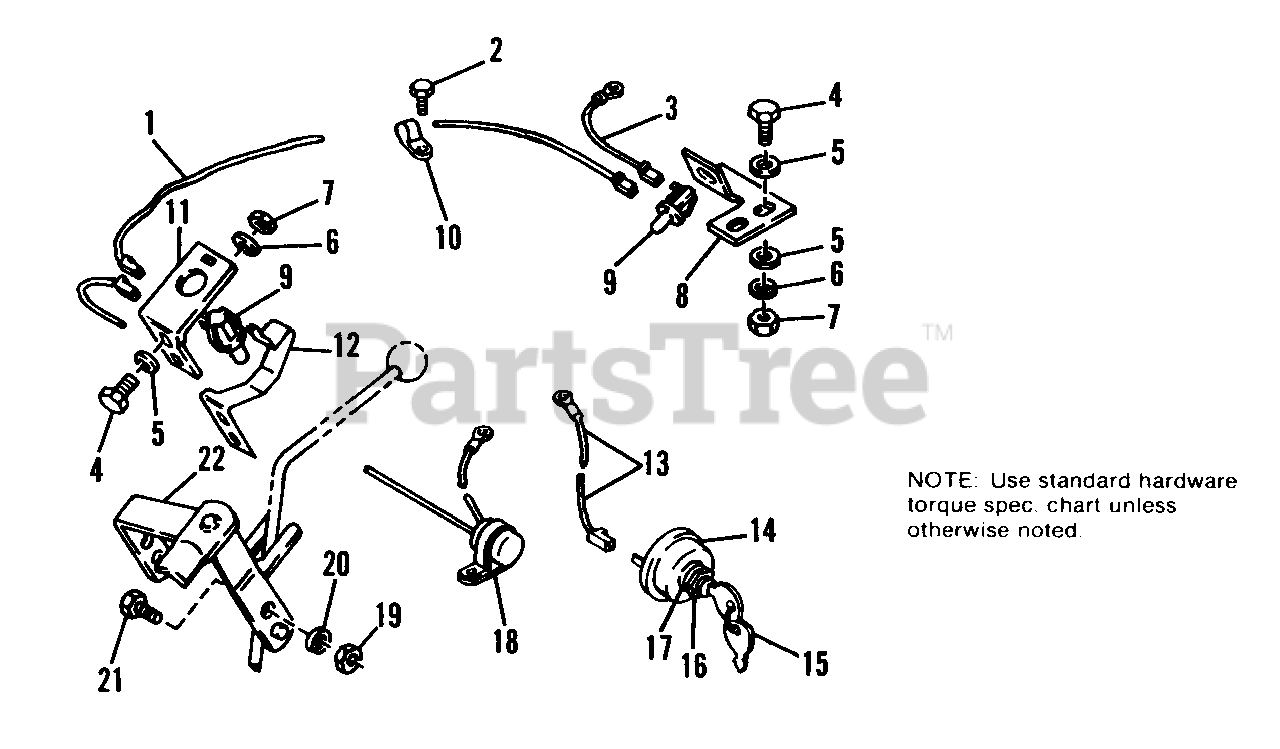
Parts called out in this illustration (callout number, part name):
2	SCREW, Hex, Taptite, 1/4-20 x 3/8
3	WIRE
4	CAPSCREW, Hex Hd., 1/4-20 x 3/4
5	WASHER, Plain, 3/16
6	LOCKWASHER, 1/4
7	NUT, Hex, Full, 1/4-20
10	CLIP, Cable
12	CLIP, Spring
14	SWITCH, W/Keys
16	NUT, Hex Special
17	LOCKWASHER, Int., 9/16
18	IGNITION, Interlock
19	NUT, Hex, Full, 5/16-18
20	LOCKWASHER, 5/16
21	CAPSCREW, Hex Hd., 5/16-18 x 3/4
22	PIVOT ASSY.
